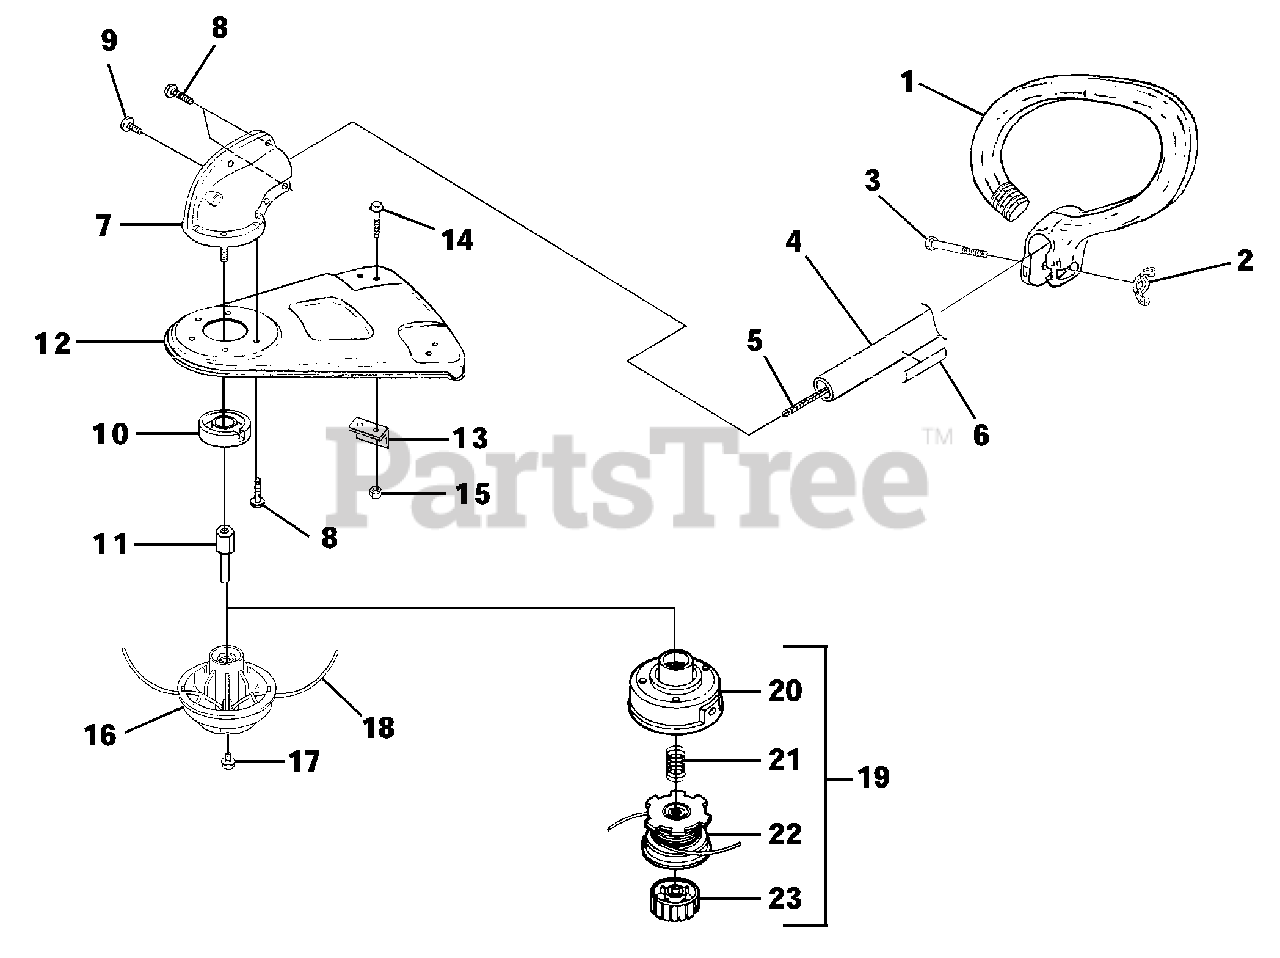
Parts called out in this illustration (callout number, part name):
1	HANDLE-Anti-Vibe
2	NUT-Wing, Washer Faced (1/4-20)
3	SCREW-Cap Hex Hd. (1/4-20 x 2")
4	DRIVESHAFT HOUSING ASSY.
5	SHAFT-Flexible
6	DECAL
7	GEARHEAD
8	Screw, Taptite Hex Hd. (10-24 x 1/2")
9	Screw-Hex Hd. (10-24 x 5/8")
10	WASHER-Flanged
11	ADAPTER-Shaft
12	GRASS DEFLECTOR KIT
13	BLADE-Cut-off
14	SCREW-Mach.Hex Hd. (10-24 X 3/8")
15	NUT-Lock Hex (10-24)
16	STRINGHEAD-Pro-Cut w/line
17	SCREW-Stringhead Retainer
18	LINE-Replacement
19	STRINGHEAD COMPLETE
20	HOUSING & EYELET (Dual Line)
21	SPRING-Compression
22	SPOOL & STRING (.095 Line)
23	RETAINER-Spool (R.H. Thread, Black)
